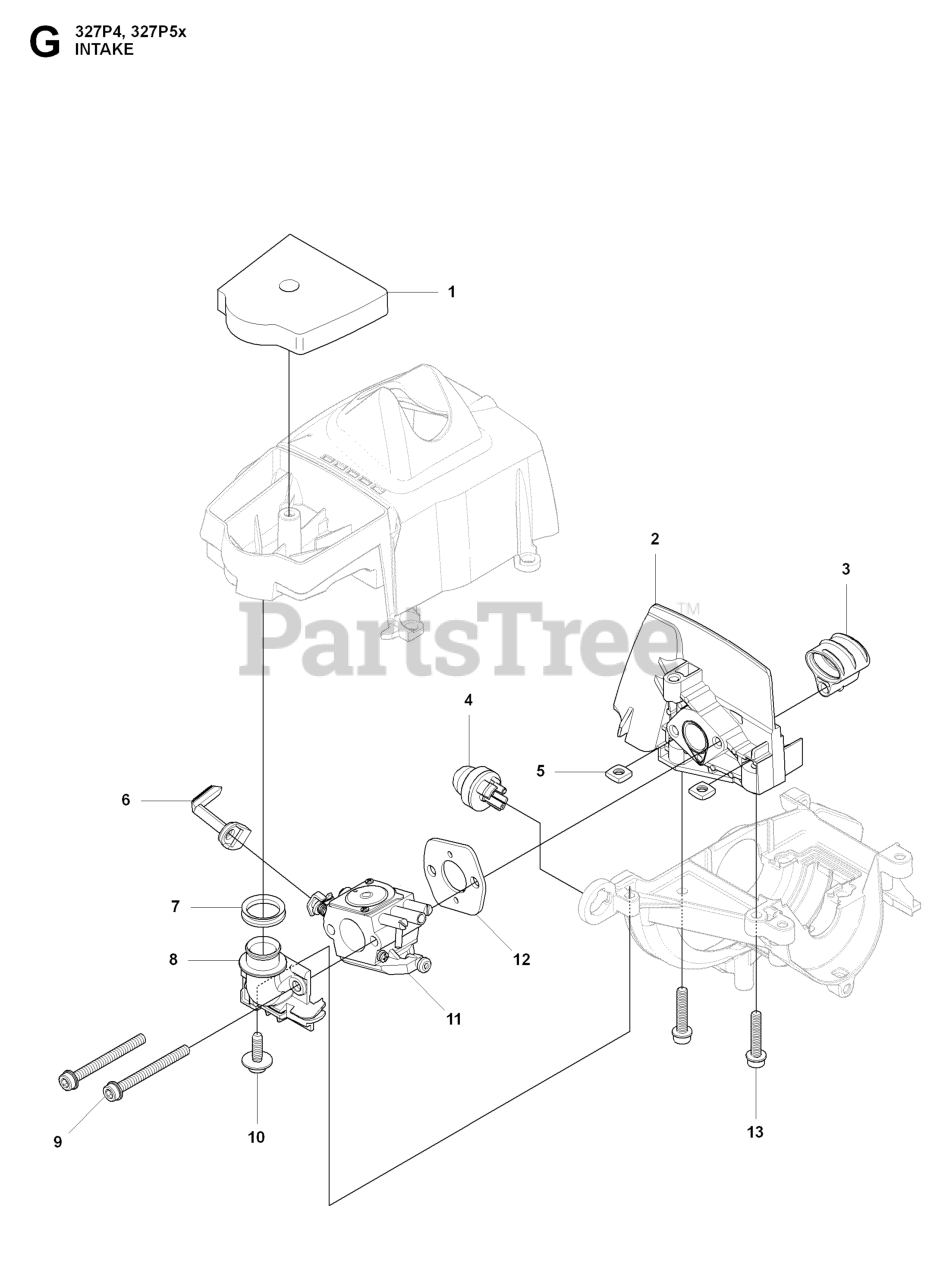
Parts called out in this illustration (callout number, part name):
1	AIR FILTER
4	AIR PURGE BUBBLE
6	CHOKE CONTROL
11	CARBURETOR
